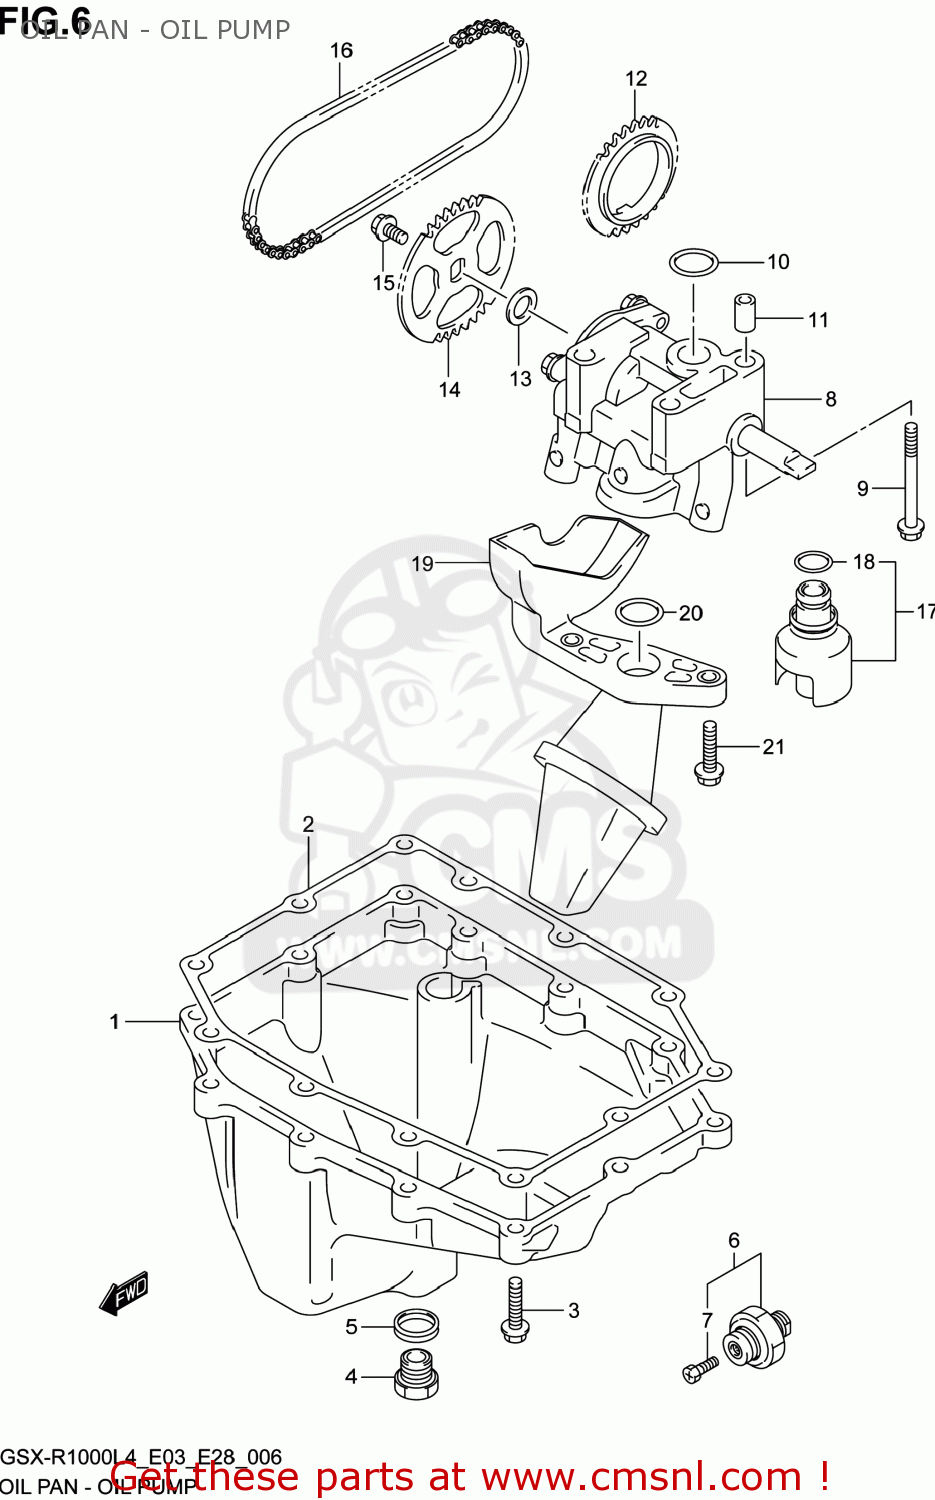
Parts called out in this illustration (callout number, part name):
1	PAN,OIL
2	GASKET,OIL PAN(ASB) (NAS)
3	BOLT
4	PLUG(14X20)
5	GASKET(13.8X18.8X4.8) (NAS)
6	SWITCH ASSY,OIL PRESSURE
7	BOLT,OIL PRESSURE SWITCH
8	PUMP ASSY,ENGINE OIL
9	BOLT
10	O RING(D:2.4,ID:15.8)
11	PIN
12	SPROCKET,OIL PUMP DRIVE
13	SHIM(10X18X0.5)
14	SPROCKET,OIL PUMP DRIVEN
15	BOLT(6X12)
16	CHAIN,OIL PUMP DRIVE
17	VALVE ASSY,OIL RELIEF
18	O RING(D:1.9,ID:13)
19	STRAINER ASSY,ENGINE OIL
20	O RING(D:2.62,ID:20.3)
21	BOLT
